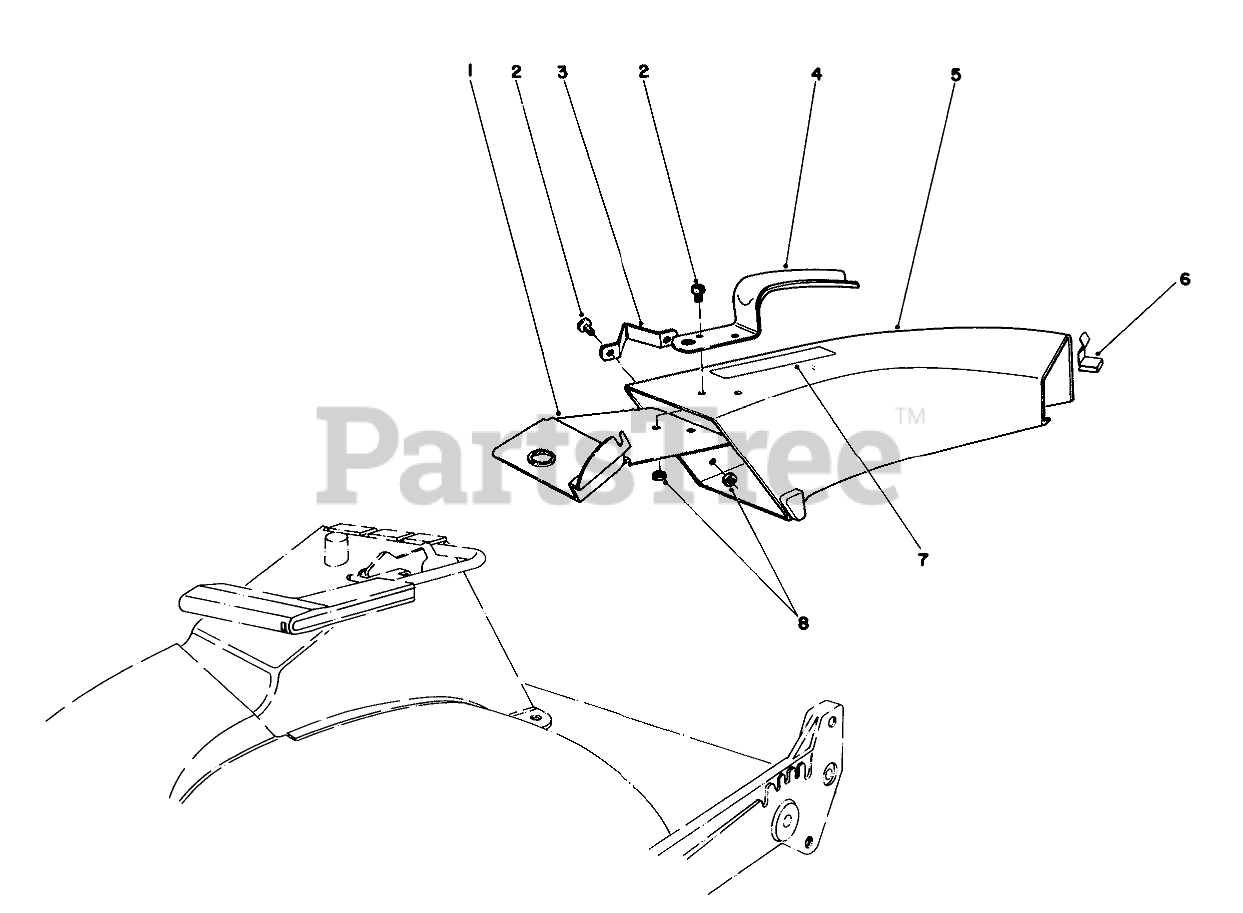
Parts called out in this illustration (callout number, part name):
1	Plate-Discharge Chut
2	10-24 X 5/8 PAN HD MS
3	SIDE BRACKET
4	CHUTE HANDLE
5	Chute Assembly
6	Clip
7	DECAL CAUTION
8	NUT-LOCK, NI
